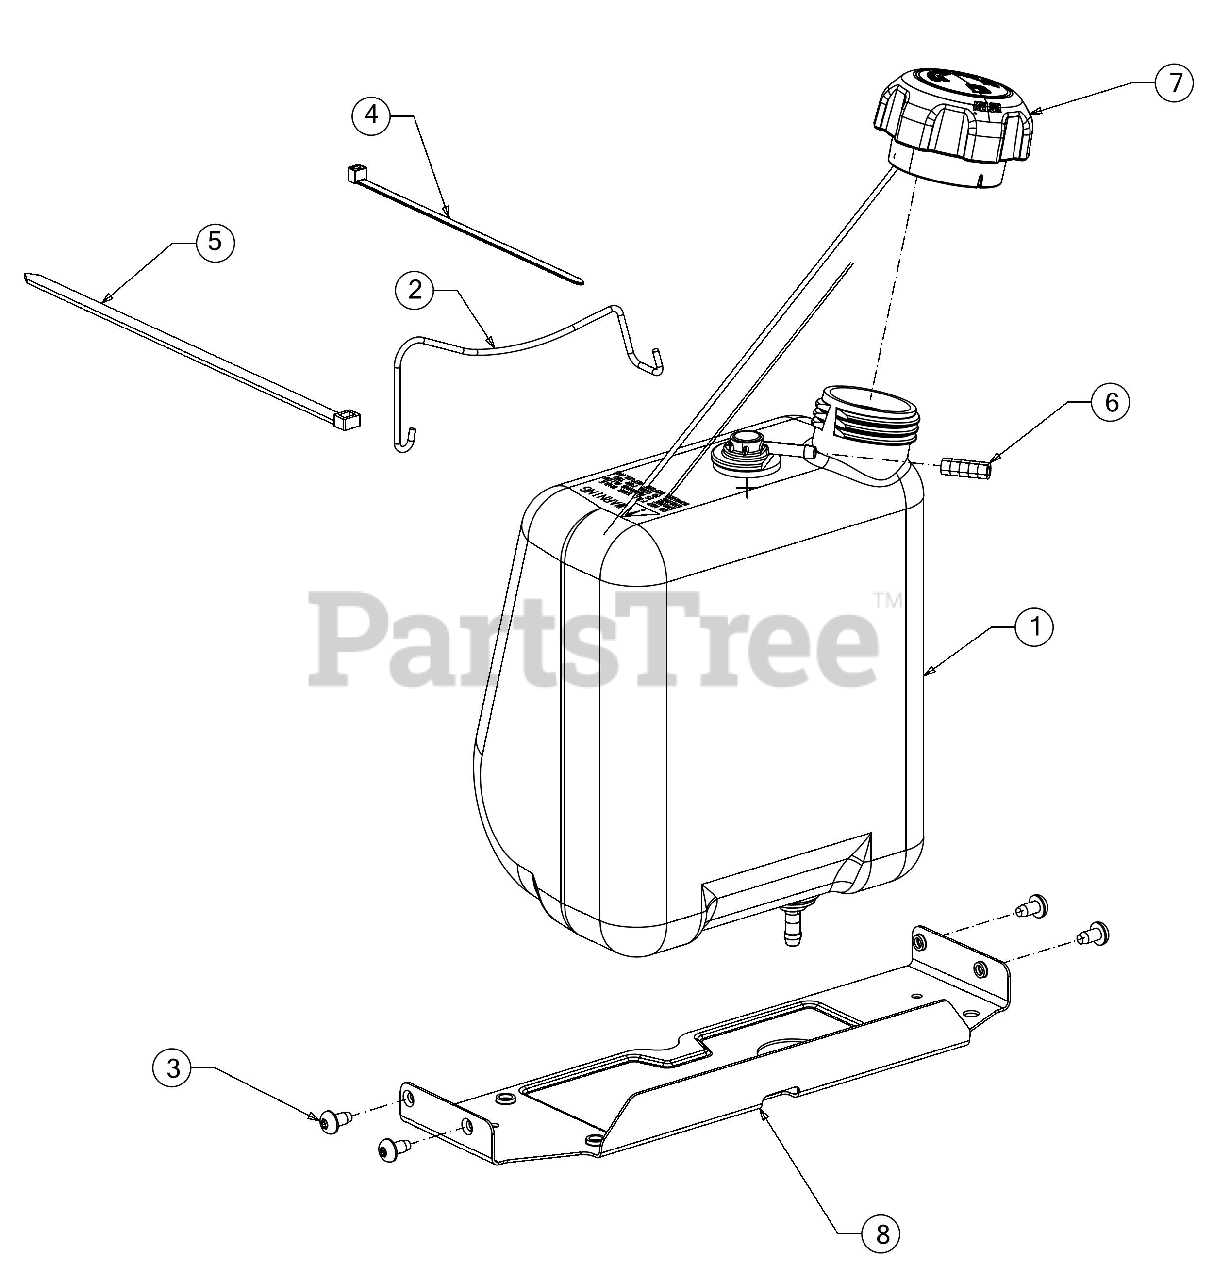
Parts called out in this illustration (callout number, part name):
1	FUEL TANK ASSEMBLY
2	BATTERY ROD ASSEMBLY
3	SCREW 1/4-20 X .5
4	CABLE TIE 7"
5	CABLE TIE 36"
6	VENT HOSE 3/16 ID
7	FUEL CAP W/TETHER
8	FUEL TANK BRACKET
